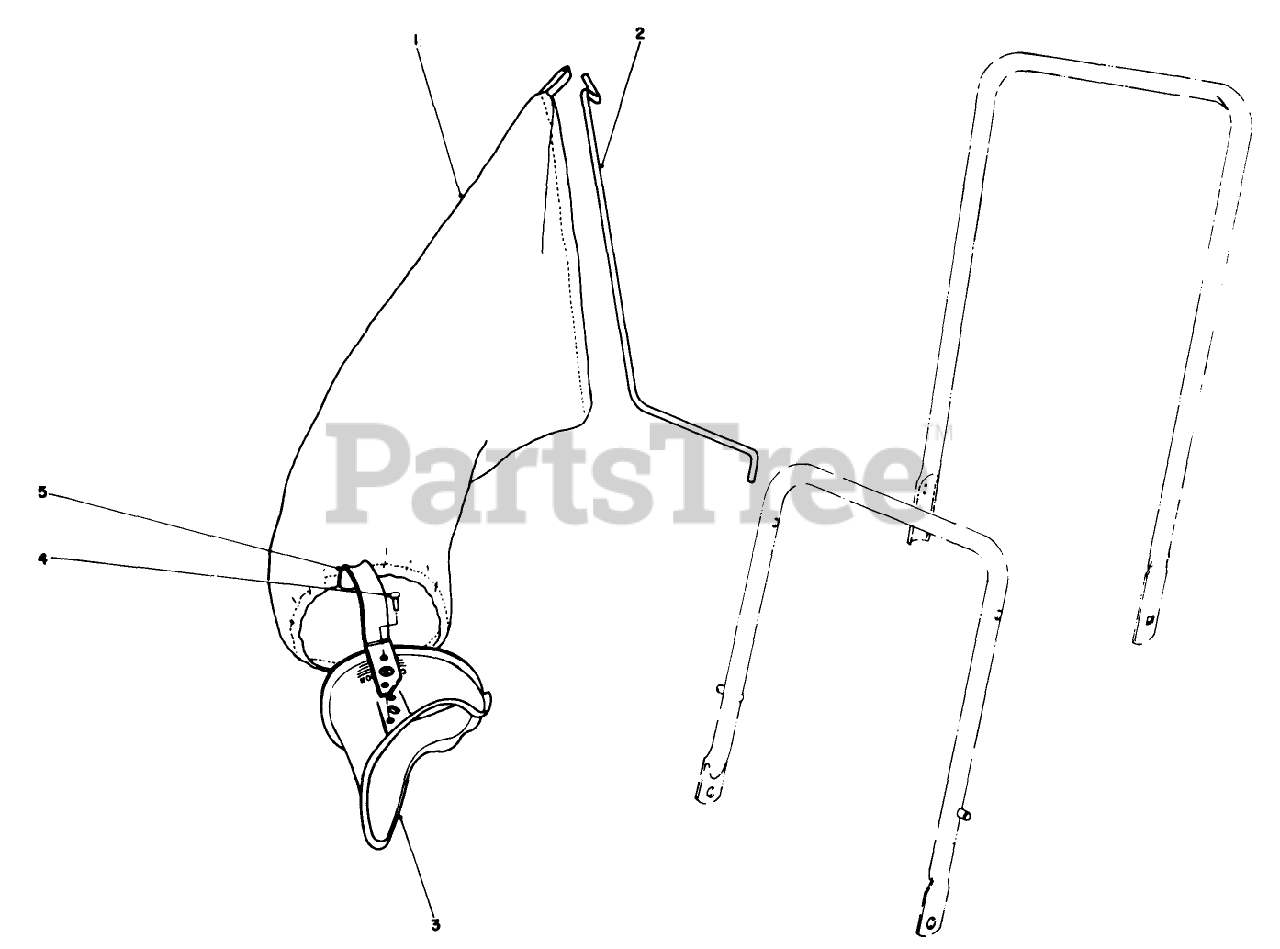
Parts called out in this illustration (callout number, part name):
2	BAG HANGER ROD
3	GRASS CHUTE ASM
4	RIVET 3/16 X 7/16
